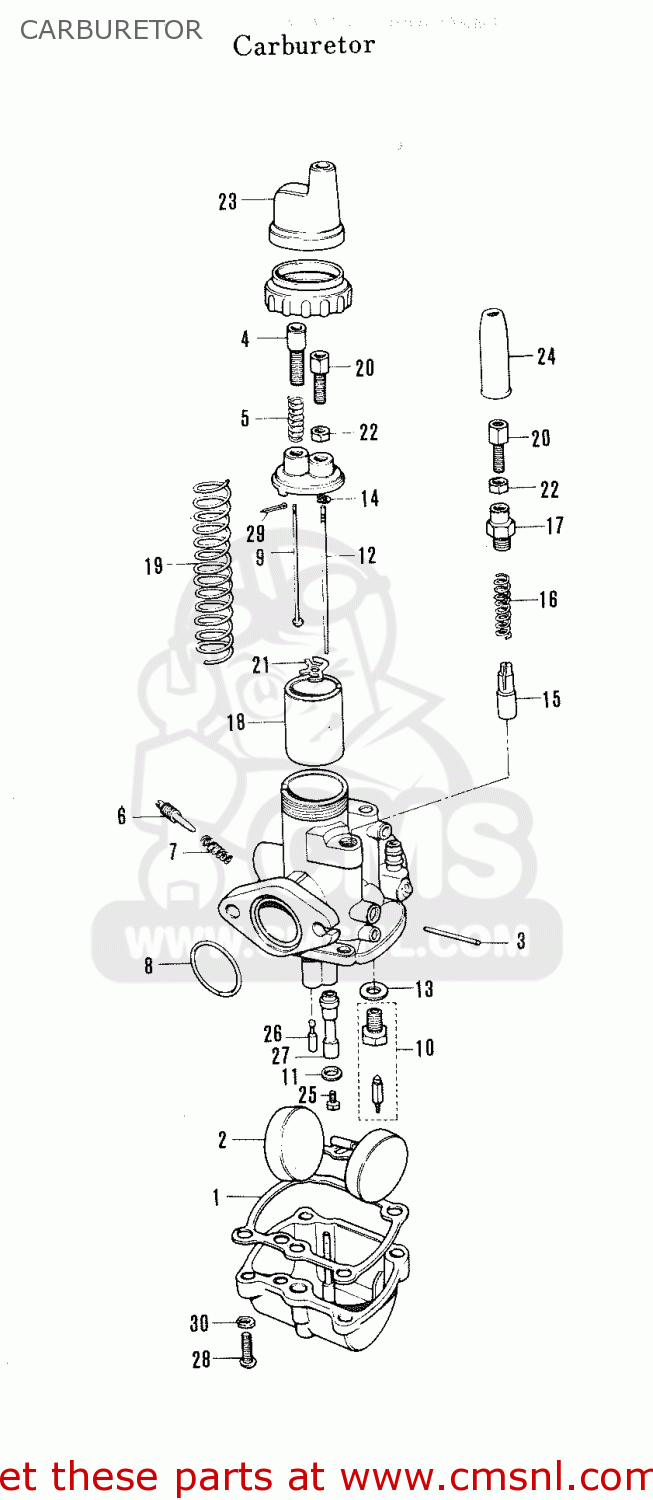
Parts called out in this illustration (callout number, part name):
1	GASKET,FLOAT CHAMBER (NAS)
2	FLOAT
3	PIN,FLOAT
4	SCREW,THROTTLE VALVE ADJUST
5	SPRING,THROTTLE SCREW
6	SCREW,PILOT AIR
7	SPRING
8	O RING,OUTLET
9	ROD,THROTTLE VALVE ADJUST
10	VALVE ASSY,NEEDLE
11	WASHER
12	NEEDLE JET
13	GASKET,NEEDLE VALVE (NAS)
14	CLIP
15	PLUNGER,STARTER
16	SPRING
17	CAP,STARTER PLUNGER
18	VALVE,THROTTLE
19	SPRING,THROTTLE VALVE
20	ADJUSTER,CABLE
21	PLATE,THROTTLE VALVE
22	NUT
23	BOOT
24	CAP,STARTER PLUNGER
25	JET,MAIN(100)
26	JET
27	JET,NEEDLE
28	SCREW
29	COTTER PIN
30	LOCK WASHER
